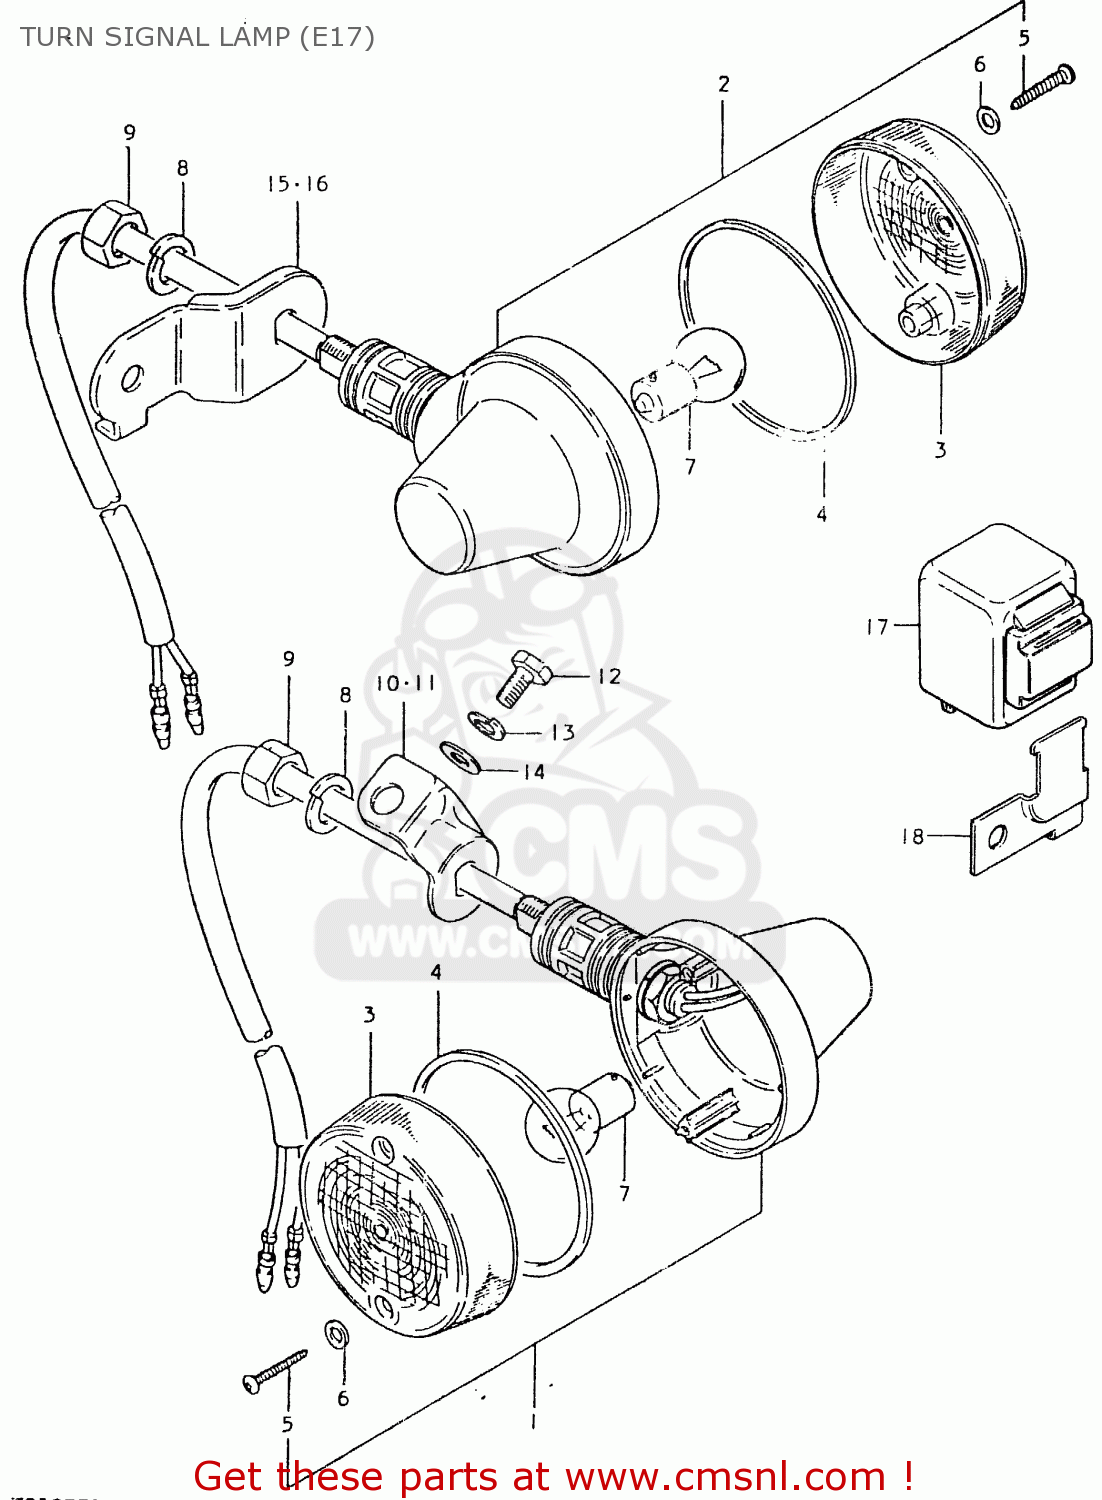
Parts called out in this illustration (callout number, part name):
1	LAMP, FRONT TURN SIGNAL
2	LAMP, REAR TURN SIGNAL
3	LENS
4	GASKET (NAS)
5	SCREW TAPP.
6	GASKET (NAS)
7	BULB (6V,21W)
8	WASHER,LOCK 12
9	NUT
10	BRACKET,TURNSIGNAL LAMP,R
11	BRACKET,TURNSIGNAL LAMP,L
12	BOLT
13	LOCK WASHER
14	WASHER
15	BRACKET,REAR TURN SIGNAL
16	BRACKET,REAR TURN SIGNAL
17	RELAY, TURN SIGNAL
18	BRACKET
